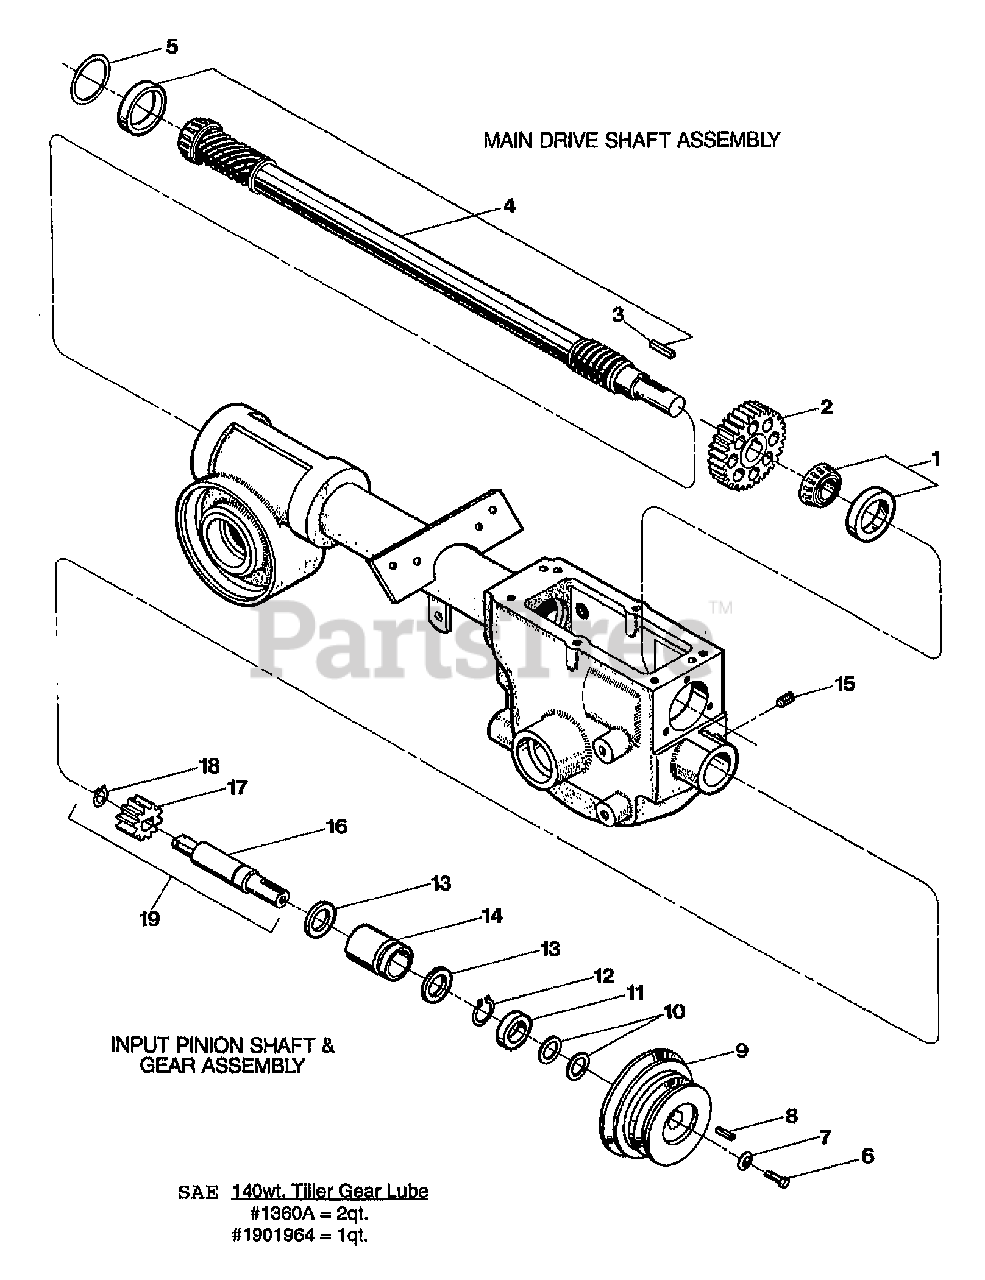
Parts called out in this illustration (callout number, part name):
1	KIT-BRG CONE&RACE-DRIVESHAFT (FRONT OF DRIVE SHAFT)
2	GEAR-SPUR 30 TEETH
3	KEY-.188 SQX1.0
4	KIT-DRIVESHAFT
5	SHIM-1.75X1.5X.01
5	SHIM-1.75X1.5X.03
5	SHIM-1.75X1.5X.005
6	SCR-HH 5/16-24X.75 G5 ZP
7	WASHER-.827X.331X.098
8	KEY-.188 SQX1.0
9	PULLEY-TRANS MACH
10	WASHER # .875 X .65 X .06
11	SEAL-PINION SHAFT PT/85030/00
12	RING-RETAIN EXT .707 ID (SNAP RING)
13	WASHER-1.022X.752X .059
14	BUSHING-1.24X.75X1.8 GRVD
15	SCR-SS 5/16-18X.375
16	SHAFT-PINION(P-V)
17	GEAR-PINION P/M
18	RING-BOWED EXT .461 ID (SNAP RING)
19	PINION W/GEAR&SNAP RING (INCL. #20791, #20792, & 9093)
